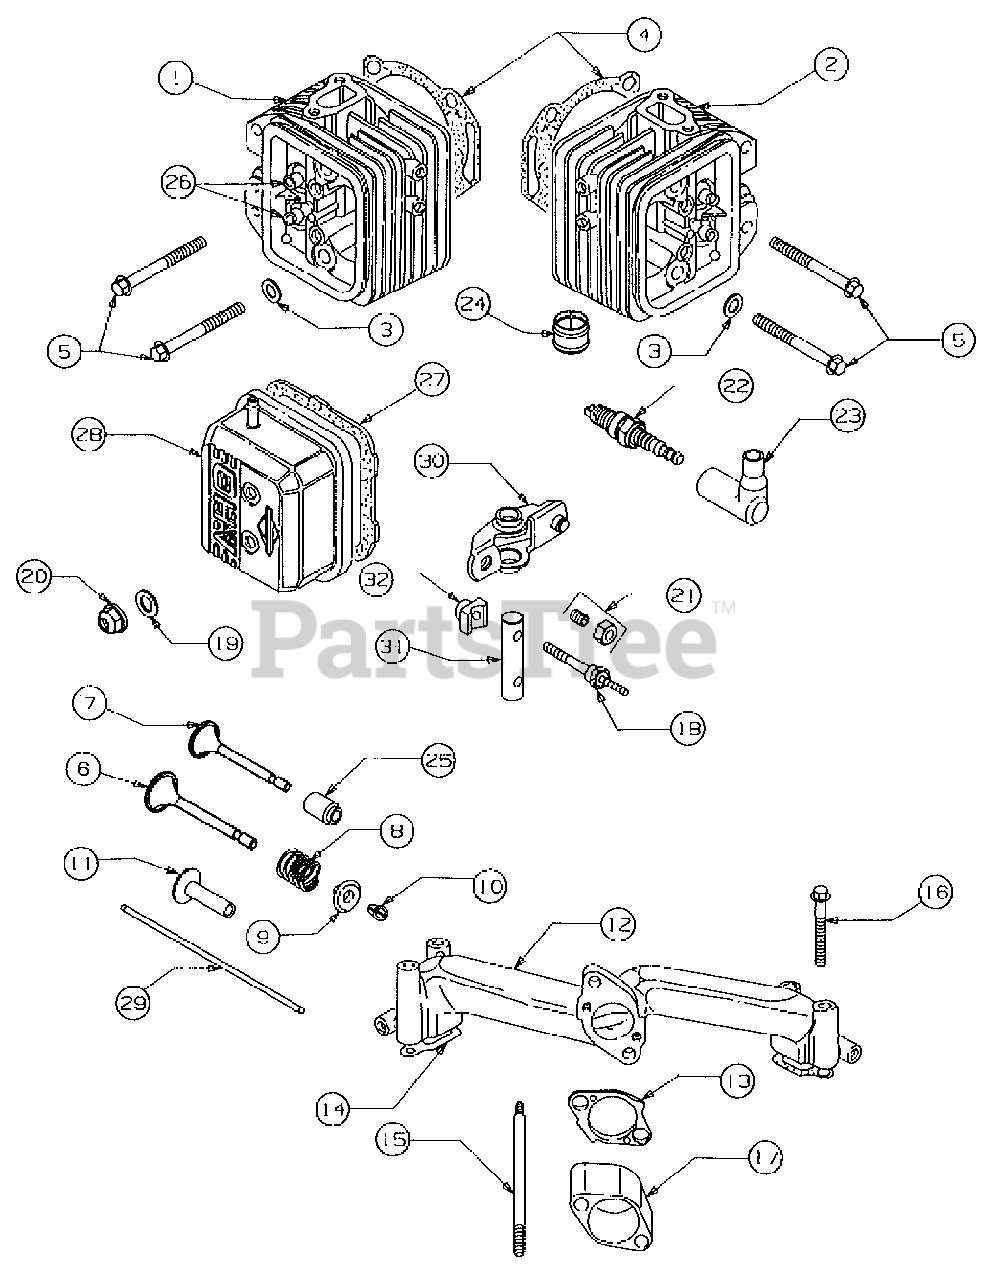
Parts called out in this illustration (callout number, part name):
1	Head, Cylinder #1
2	Head, Cylinder #2
3	Washer, Cylinder Head
4	Gasket, Cylinder Head
5	Screw, Cylinder Head
6	Valve, Exhaust
7	Valve, Intake
8	Spring, Valve
9	Retainer, Valve Spring
10	Retainer, Valve
11	Tappet, Valve
12	Manifold, Intake
13	Gasket, Carburetor Mtd
14	Gasket, Intake Manifold
15	Stud, Carburetor Mtd
16	Screw, Sem
17	Spacer, Carburetor
18	Stud, Rocker Arm
19	Washer, Valve Cover
20	Nut, Nylock
21	Screw, Valve Adjusting
22	Plug Spark
23	Elbow, Spark Plug
24	Liner, Exhaust Port
25	Seal , Valve Guide
26	Guide, Valve
27	Gasket, Valve Cover
28	Cover, Valve
29	Rod, Push
30	Arm, Rocker
31	Shaft, Rocker Arm
32	Support, Rocker Arm
